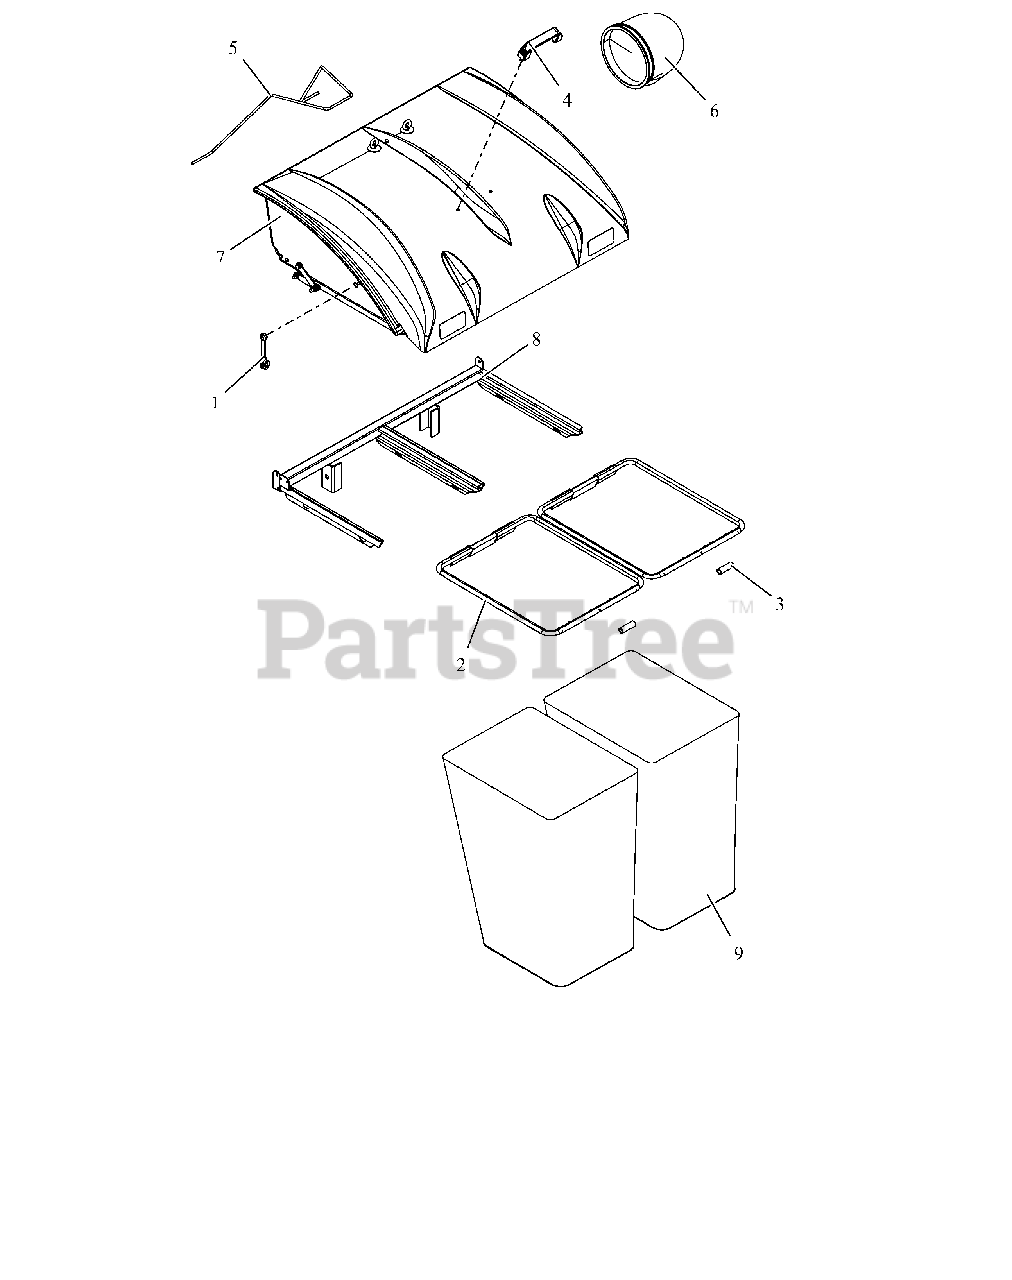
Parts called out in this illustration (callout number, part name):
1	RUBBER HOOD STRAP
2	FRAME, BAG
3	HOSE, VINYL
5	ROPE, BAGGER RELEASE
6	ELBOW, PECO BAGGER
7	HOOD ASM PECO 2 BAG
8	FRAME ASM PECO 2 BAG
9	PECO BAGGER BAG
